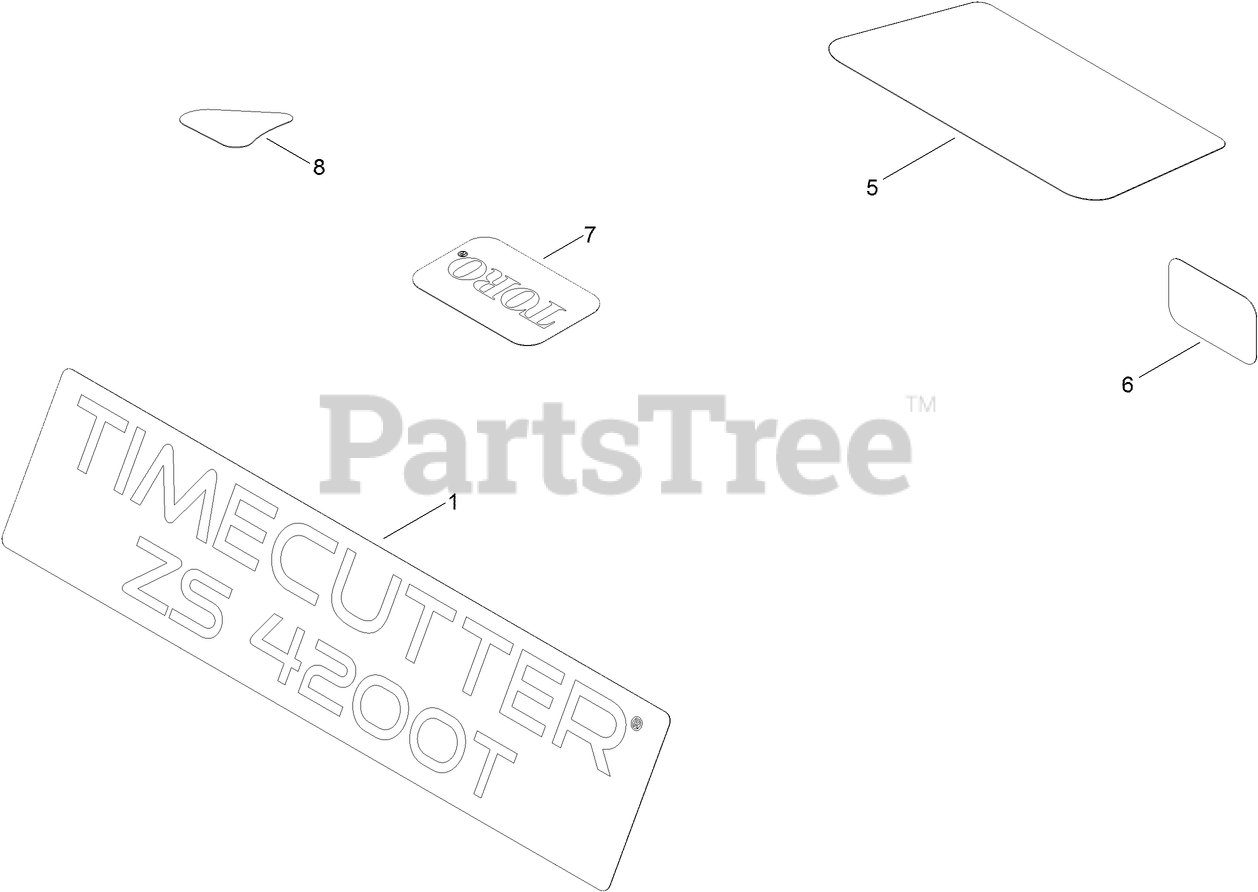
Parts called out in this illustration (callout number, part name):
1	DECAL-TIMECUTTER
5	DECAL-ENGINE
6	PLACARD-INTAKE
8	DECAL-DRAIN, OIL
